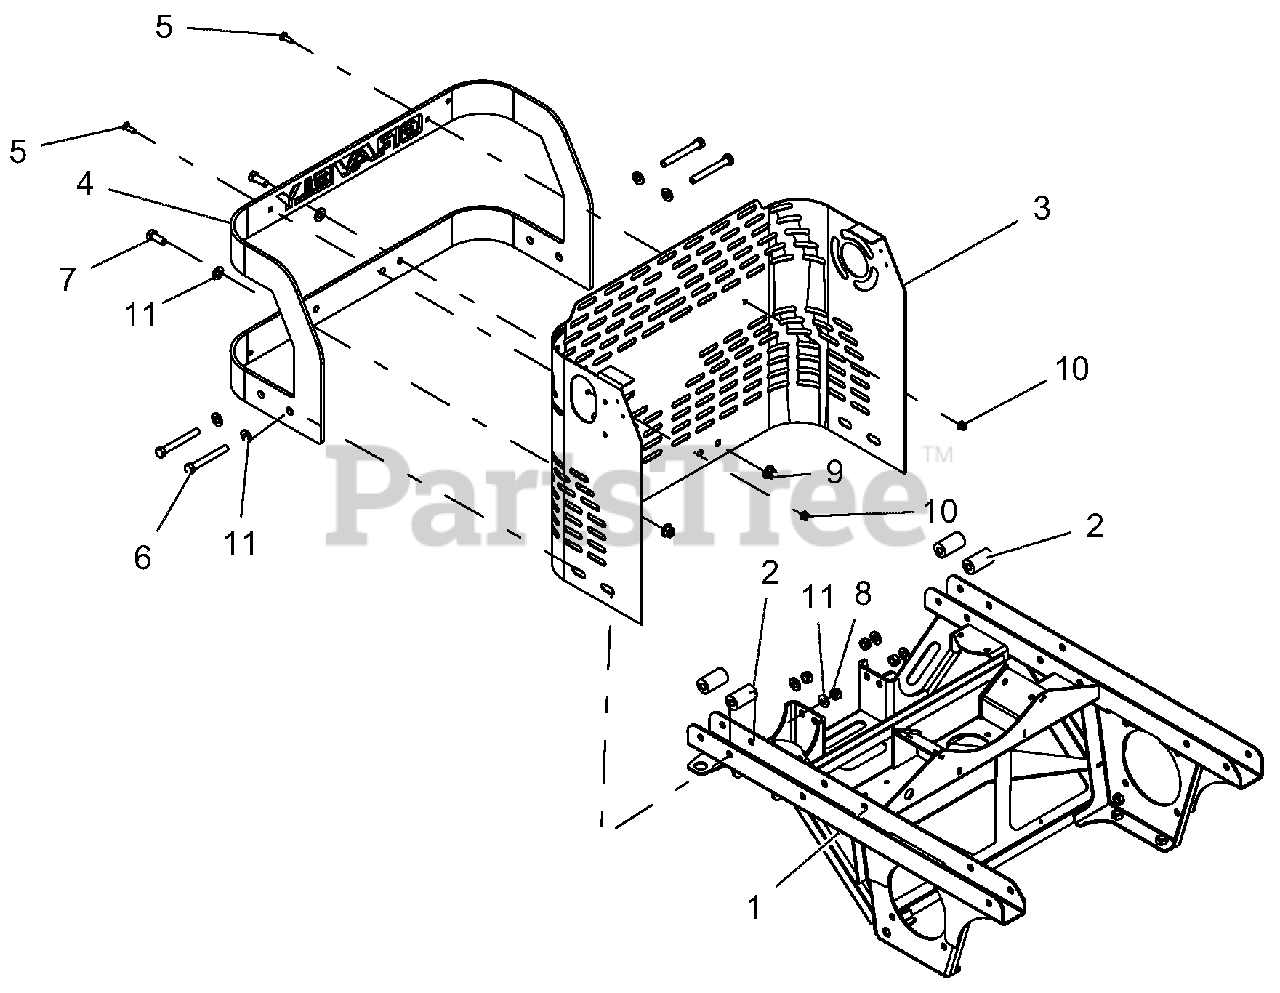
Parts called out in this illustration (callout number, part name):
1	WLDMT, ENGINE/ TRANSMISSION FRAME-RED
2	SPCR, BUMPER PT 400, DIESEL
3	GUARD, REAR PT400 DIESEL
4	BUMPER, PT400 REAR
5	@BLT-RDHDSQSHNK .31-18X1.00 G5 Y
6	BLT-HEX .50-13X4.00 GR5 YWZC
7	BLT-HEX .50-13X1.25 GR5 YWZC
8	@NUT-LK-CTR .50-13 YWZC
9	NUT-LK-NYL-FLG .50-13 YWZC
10	NUT-LK-NYL-FLG .31-18 YWZC
11	@WSHR-FL-STL.531X1.06X.095YWZC
